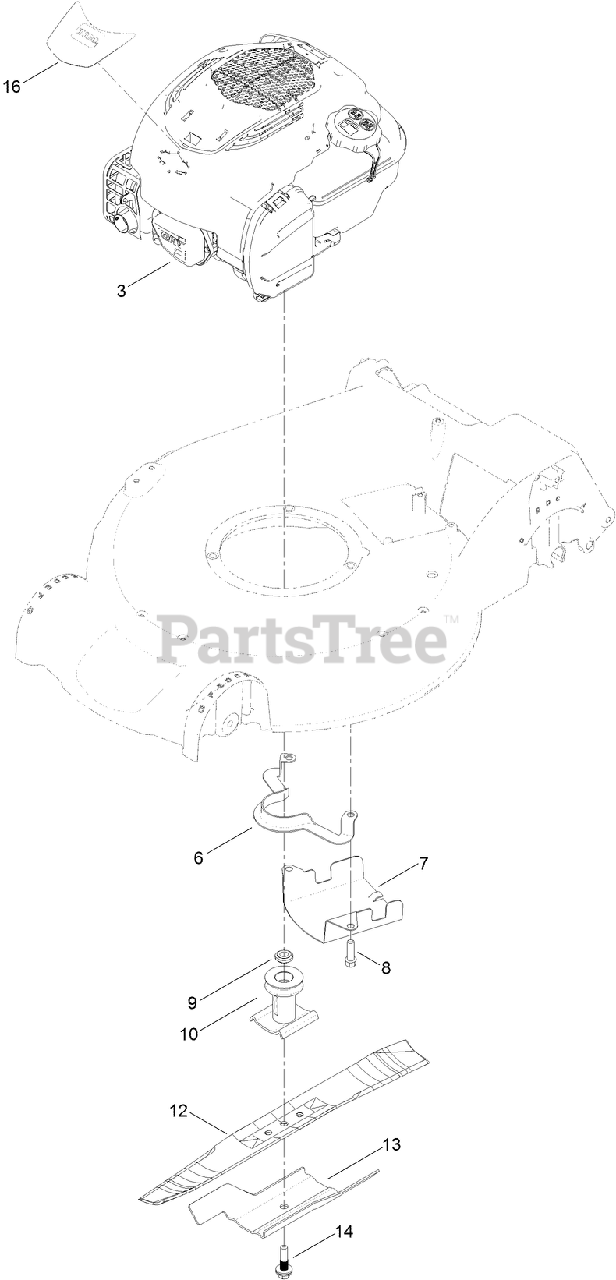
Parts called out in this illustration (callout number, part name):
6	GUIDE-BELT
7	SHIELD-GRASS
8	SCREW-TAPTITE
9	Spacer-Driver
10	DRIVER-BLADE
12	BLADE-RECYCLING
13	Accelerator-Blade
14	BOLT-BLADE
16	DECAL-SHROUD
